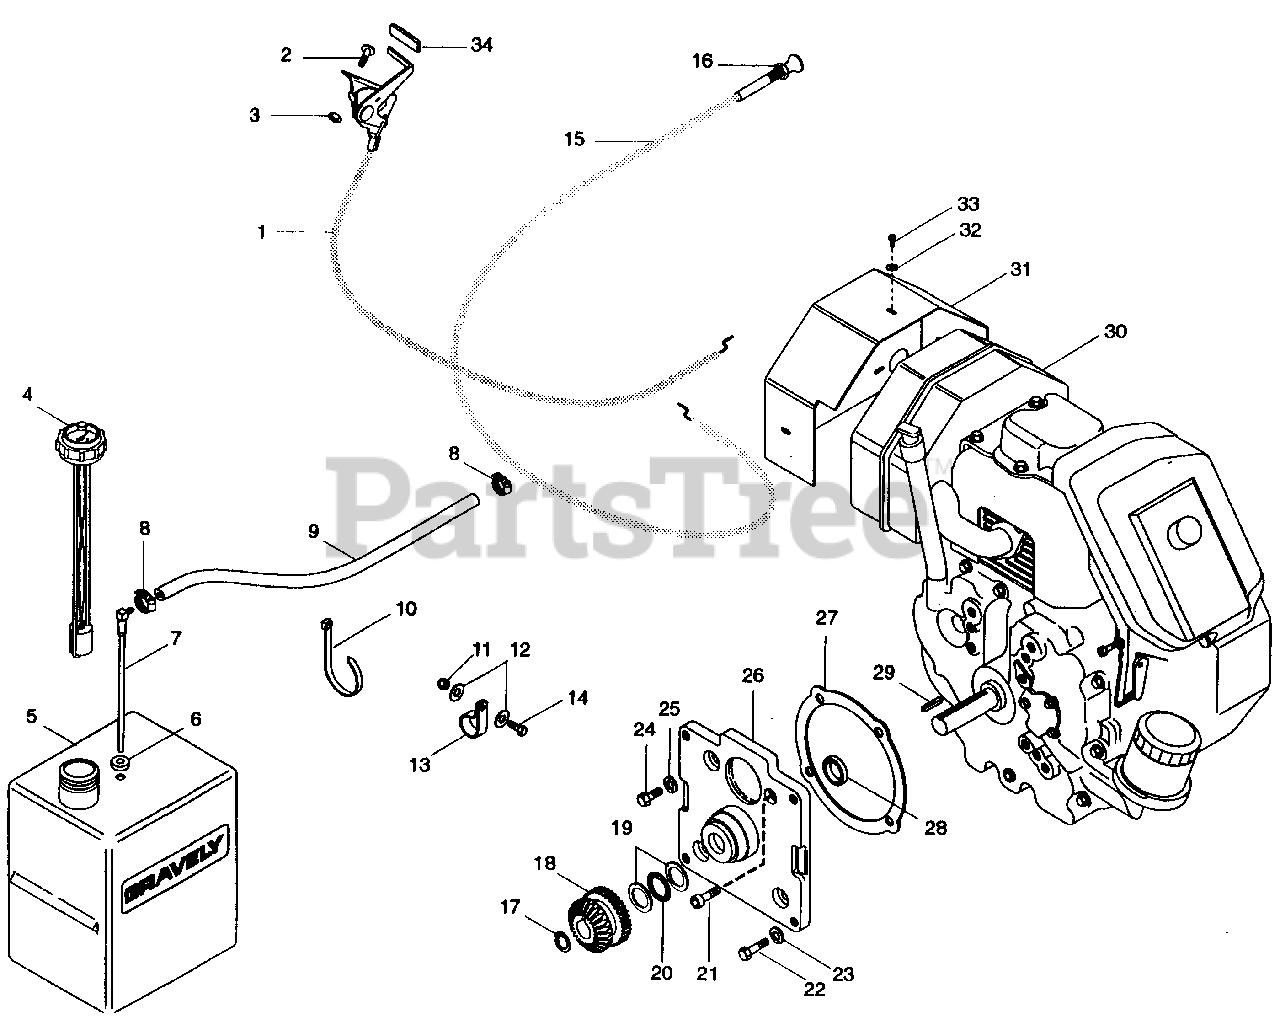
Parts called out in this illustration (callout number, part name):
1	THROTTLE CABLE
2	SCR-MCH 10-32 X .50 PH D
3	NUT-LK 10-32 NY PL
4	GA, FUEL
5	TANK, FUEL
6	BUSHING
7	FTG, TANK
8	CLAMP-HOSE
9	GAS LINE-BULK
10	TIE CABLE
11	NUT-LK-NYL .312-18 PL
12	WSHR-FL-STL .344 X .688 X .065
13	CABLE CLAMP
14	BLT-HEX .31-18 X 1.00 PL GR 5
15	CONTROL, CHOKE
16	NUT-JAM .375-24 PL
17	RG-RTNG-INT 1.249 X .050
18	INPUT GEAR
19	WSHR-THRST 1.125 X 1.750 X .123
20	BRG-N-THRST 1.74 X 1.127 X .078
21	SCR-SKH .44-14 X 1.00
22	BLT-HEX .50-13 X 1.25 PL GR 5
23	WSHR-LOCK .50 REG.
24	BLT-HEX .44-14 X 1.125
25	WSHR-LOCK .438 X .133 HVY
26	ADPT, ENGINE
27	GSKT, ADAPTER
28	SEAL 1.125 X 1.628 X .250
29	KEY, SQ .248 X 1.25 X .248
30	ENG, 14-HP KOHLER, PS-1810
31	WLDMT, HEAT SHIELD
32	WSHR-FL-STL .219 X .500 X .049 PL
33	SCR-DR 8-18 X .50
34	GRIP
